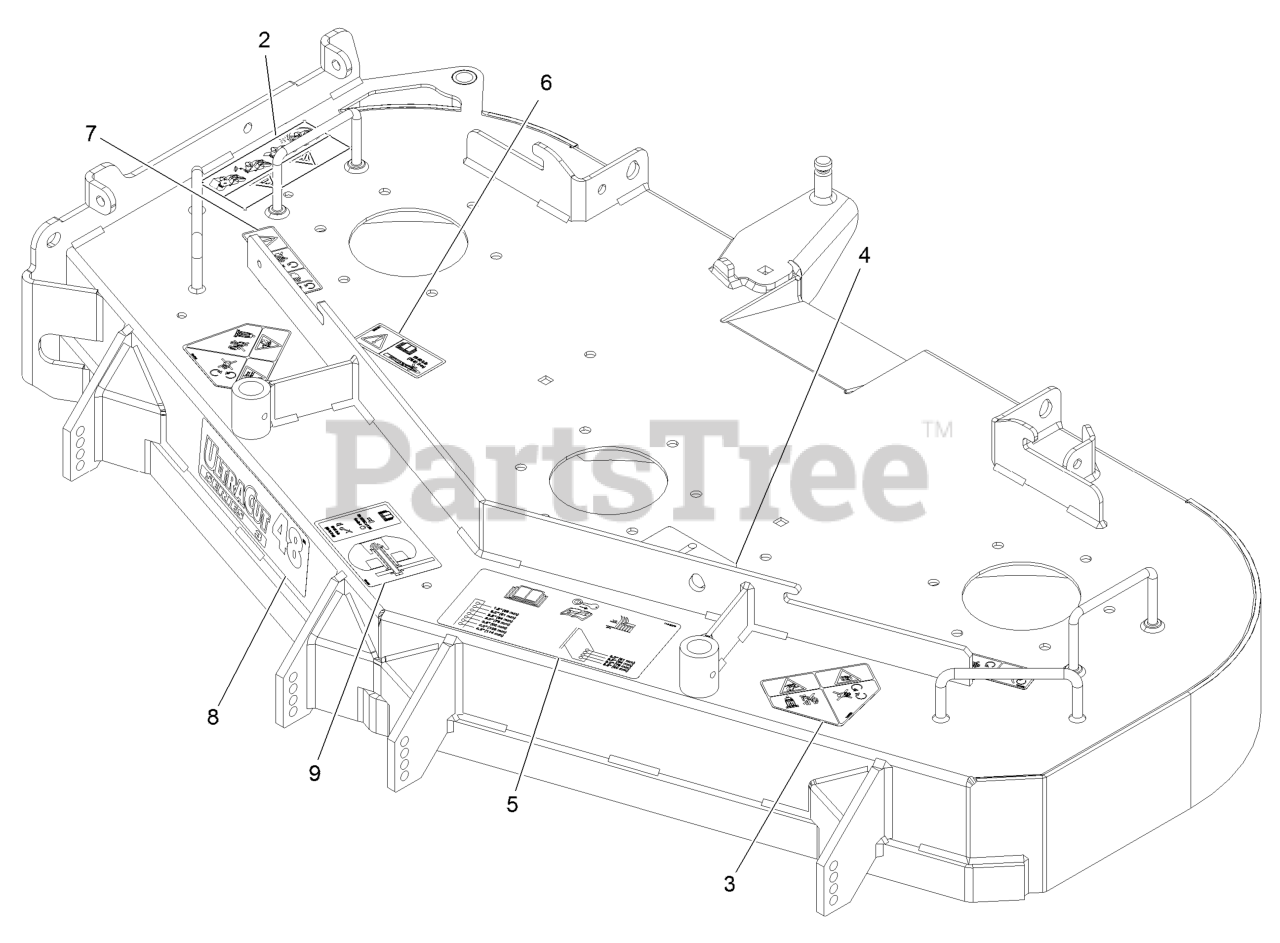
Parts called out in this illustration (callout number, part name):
2	DECAL-WARNING, BAGGER
3	DECAL-DANGER
4	DECAL-BELT ROUTING
5	DECAL-ANTI-SCALP
6	DECAL-BOLT TORQUE
7	DECAL-COVER, MISSING
8	DECAL-ULTRACUT 48 SERIES
9	DECAL-ROLLER MOUNTING
